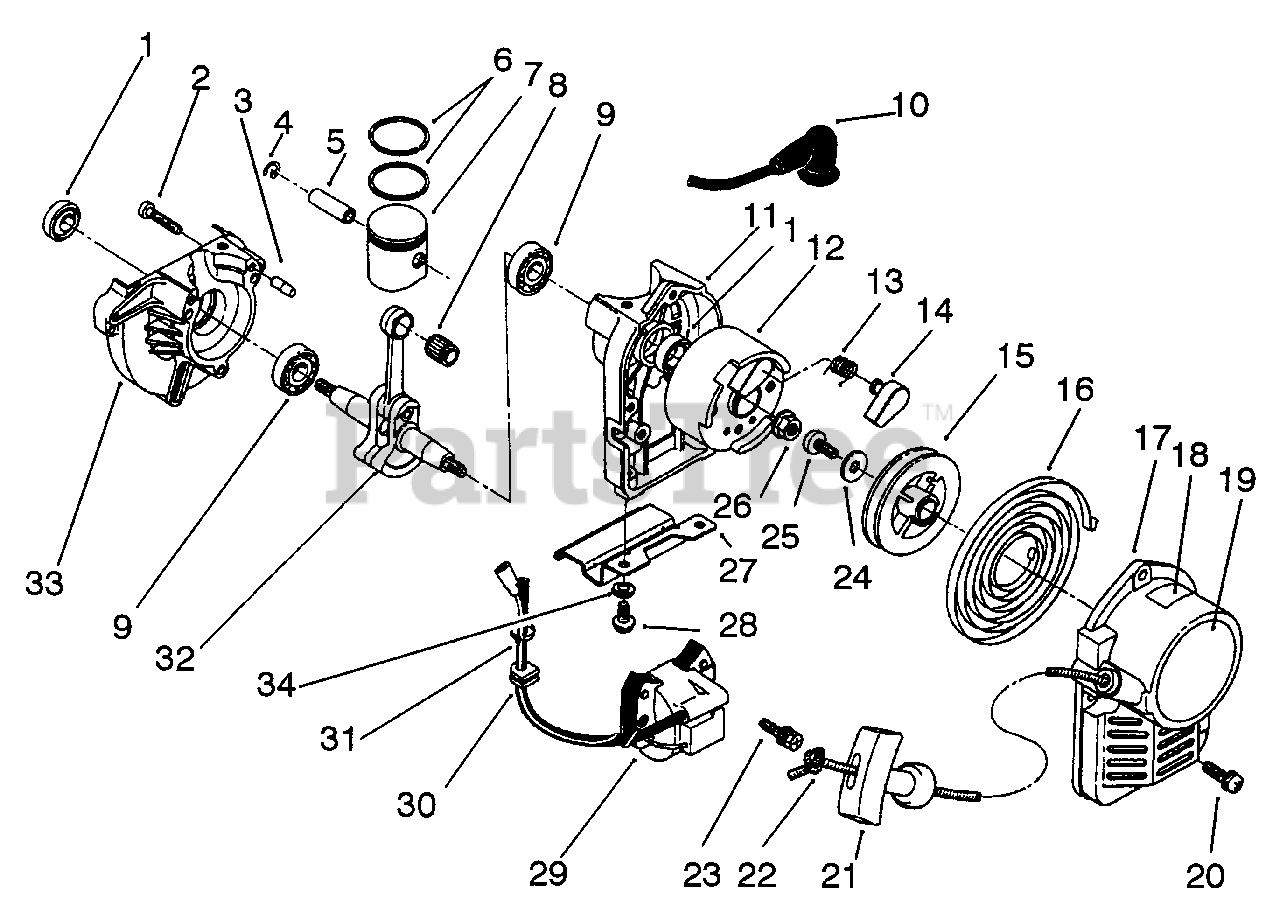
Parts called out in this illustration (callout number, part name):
1	Seal-Oil
3	Pin-Dowel
4	Clip-Piston Pin
5	Pin-Piston
6	Ring-Piston
7	Piston Assembly (Incl. Ref. #5)
8	Bearing-Needle
9	Bearing-Ball
10	Cap-Plug
11	Case-Starter Side
12	Rotor Assembly (Incl. Ref. #13-14)
13	Spring-Return
16	Spring-Spiral
17	Case-Starter
18	Decal-Hot
19	Decal-Toro
20	Screw/Washer
21	Knob-Starter
22	Rope-Starter
23	Bolt/Washer
29	Coil-Ignition
32	Crankcase Assembly
33	Case-Drive Side
34	Washer-Lock
